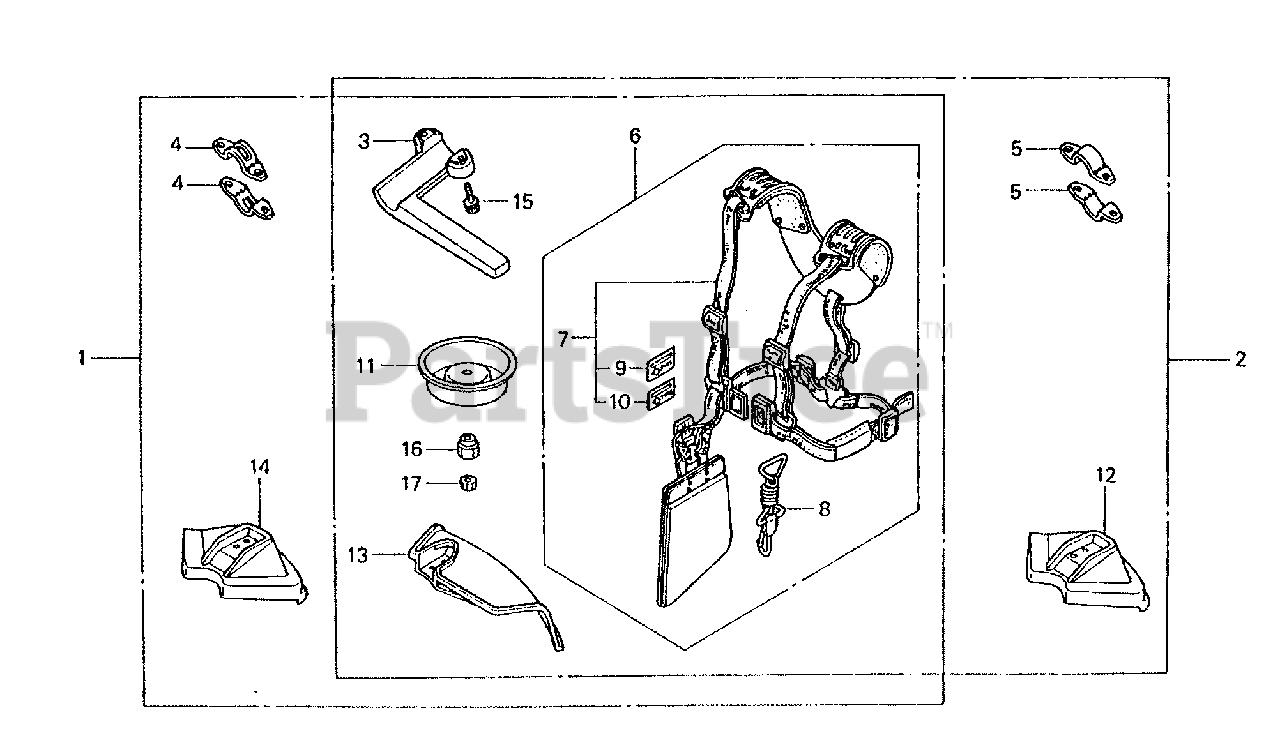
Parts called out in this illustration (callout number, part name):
2	BARRIER KIT
3	BAR, LOOP HANDLE
5	HOLDER, LOOP HANDLE
6	BELT ASSY., SHOULDER
7	BELT, SHOULDER
8	HOOK, SHOULDER BELT
9	MARK, QUICK RELEASE (E)
10	MARK, QUICK RELEASE (F)
11	COVER, NUT
12	DEFLECTOR, GRASS
13	DEFLECTOR, GRASS
15	BOLT, SOCKET (6X18)
16	NUT, HEX. (10MM)
17	NUT, HEX. (6MM)
